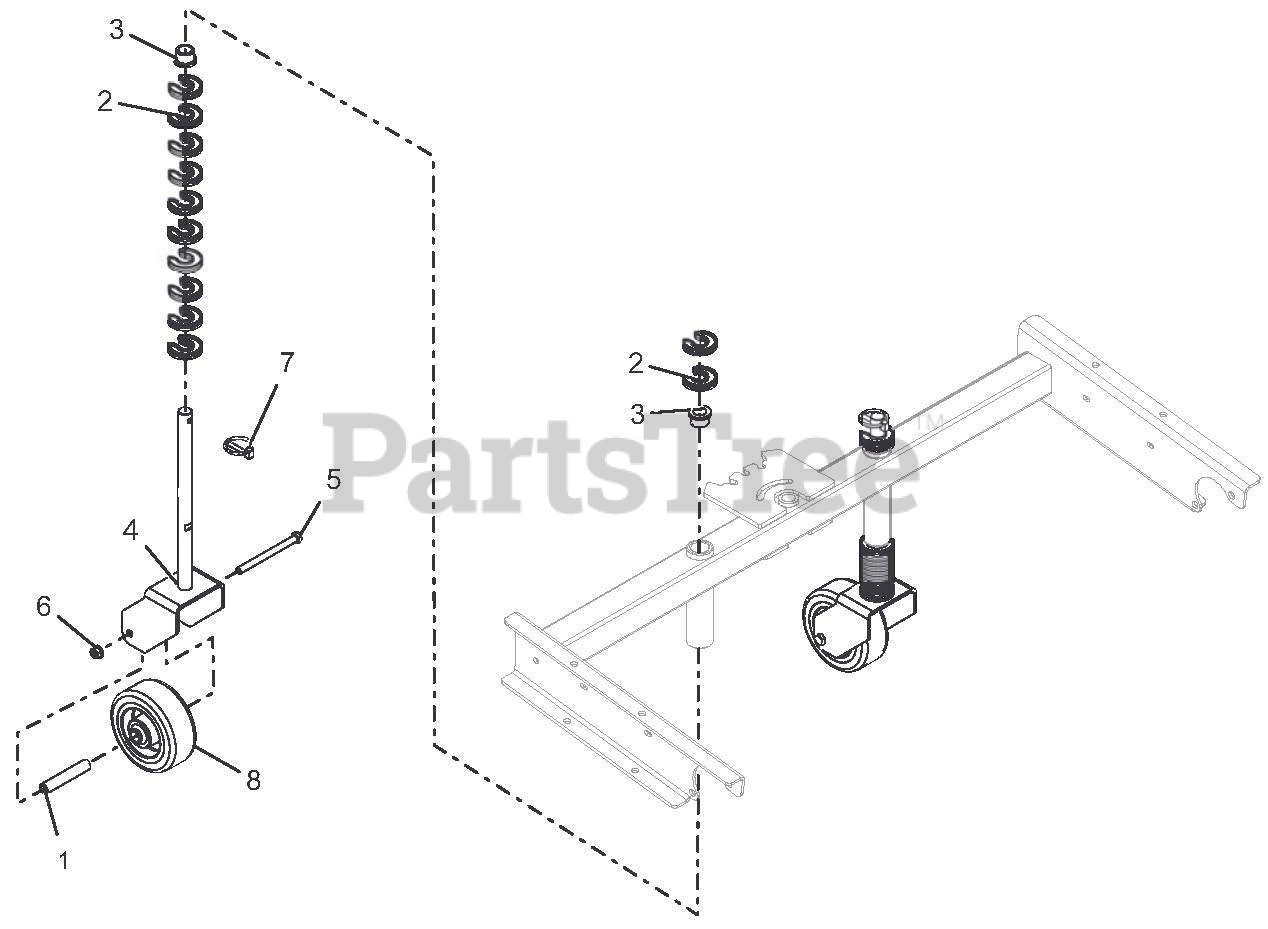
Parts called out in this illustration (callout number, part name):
1	SPACER, CASTER WHEEL
2	CLIP-HOC FIXED
3	BUSHING, FLANGE .75X.75X1.0
4	FORK, CASTER
5	@BLT-HEX .38-16X4.50 GR5 YWZC
6	@NUT-LK-TOP-FLG .38-16 YWZC
7	PIN, 1/4X1-9/16 LYNCH
8	WHEEL, CASTER - 5"OD
